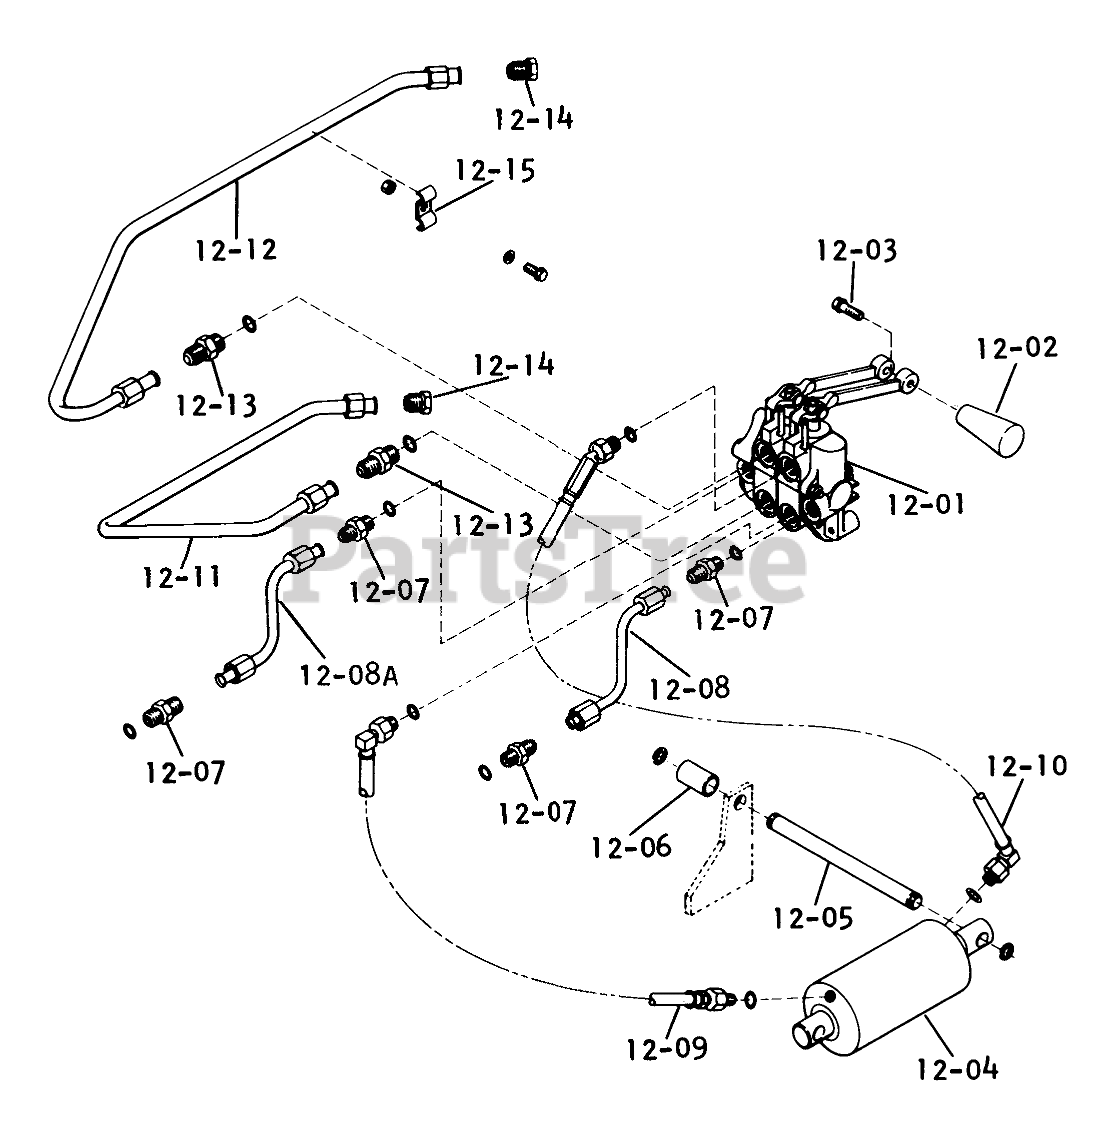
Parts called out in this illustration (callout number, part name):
12-01	Valve Assy.
12-03	SCREW
12-04	Cylinder
12-05	Cylinder Pivot
12-06	Spacer
12-07	FITTING
12-08	PRESSURE TUBE ASSY
12-08A	ASSY TUBE PRESSURE
12-09	ASSY-HYDRAULIC HOSE
12-10	Hydraulic Hose Assy
12-11	Front Tube Assy
12-12	Rear Tube Assy
12-13	FITTING
12-15	Clamp Tube
